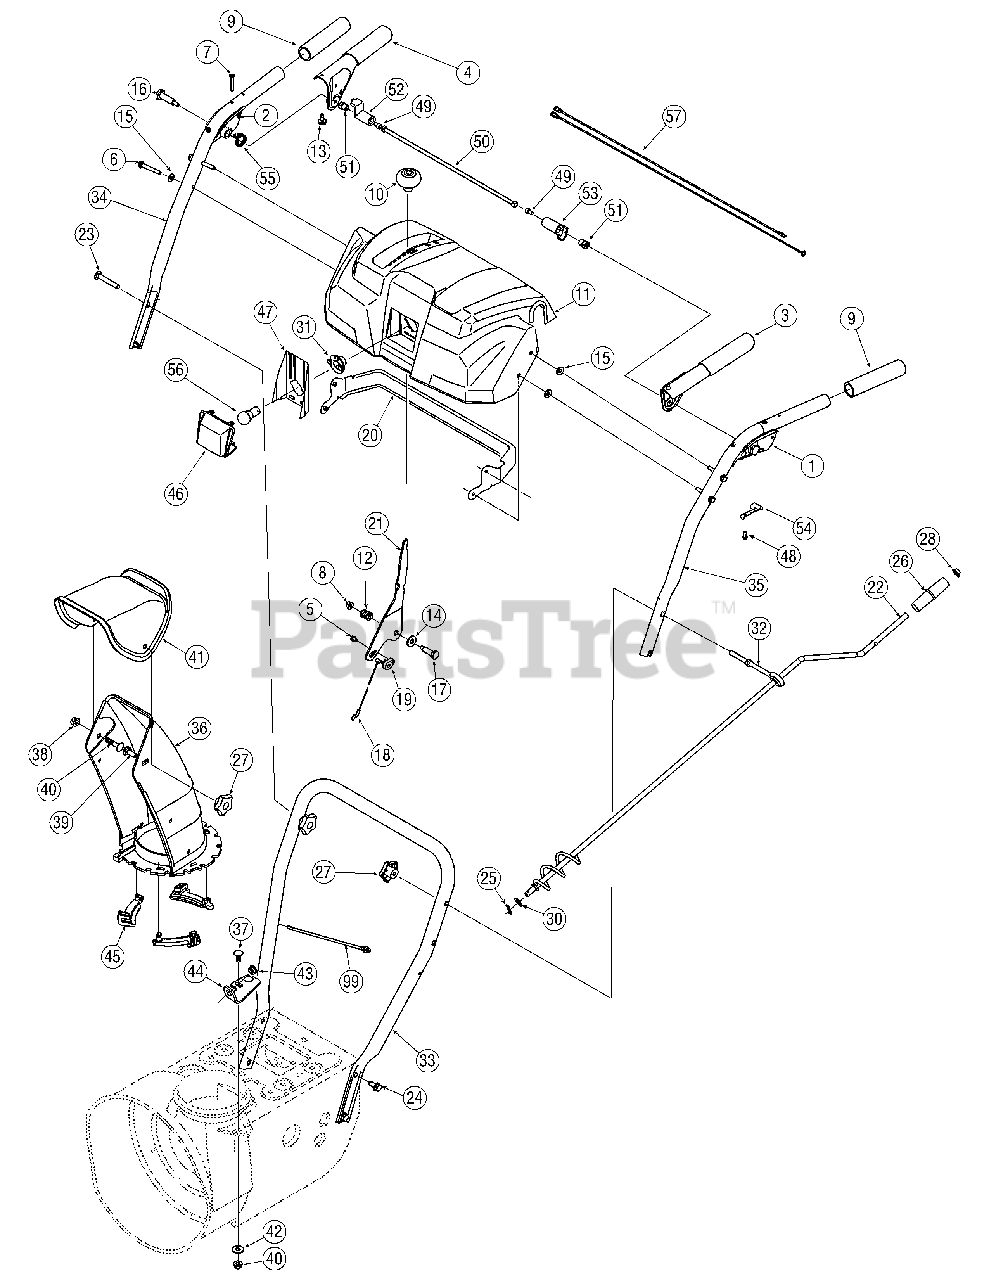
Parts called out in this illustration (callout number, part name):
1	Handle Assembly, Lock, LH
2	Handle Assembly, Lock, RH
3	Handle Ass’ y, Engagement LH
4	Handle Ass’y, Engagement, RH
5	Screw, #10-16, 0.500
6	Screw, 1/4-20, 1.750
7	Screw, Machine, #10-24, 1.375
8	Nut, Flange Lock, 1/4-20, Nylon
9	Grip, 1.0 ID x 5.0
10	Knob, Shift
11	Handle Panel, O-Style
12	Spring, .39 x .60 x .88
13	Bumper, Rubber, .62 OD x .22
14	Washer, Flat, .385 x .870 x .092
15	Washer, Flat, .25 x .630 x .0515
16	Screw, Shoulder, .43 x 1.34, 1/4-20
17	Screw, Shoulder, .374 Dia. x 1.05
18	Cable, Speed Selector
19	Barrel Holder, Cable, LH
23	Screw, Carriage, 5/16-18, 2.25
24	Screw, 5/16-18, 0.75, Gr5
25	Pin, Cotter, .072 x 1.13
26	Crank Knob, 1.0 Dia. x 3.2, Black
27	Knob Assembly, Wing Nut, 5/16-18
28	Cap, Push, 3/8 Rod
29	Grommet, .44 ID x .94 OD x .50
30	Washer, Flat, .375 x .738 x .063
31	Light Socket
32	Eye Bolt, Chute Crank
36	Chute, Lower, 5.0 Diameter
37	Bolt, Carriage, 5/16-18, 1.0
38	Nut, Flange Lock, 5/16-18, Nylon
39	Bolt, Carriage, 5/16-18, 1.0
40	Bolt, Carriage, 5/16-18, .750
41	Chute, Upper, w/ Label
42	Washer.349 ID x .879 OD x .063
43	Bushing, Plastic, .380
45	Flange Keeper, Chute
47	Reflector Label, Lens
48	Screw, #8-16 x 0.50
49	Screw, 1/4-20 x.375
50	Pivot Rod
51	Shoulder Nut, 1/4-20
52	Lock Plate
53	Clutch Lock Cam
54	Clutch Lock Spring
55	Torsion Spring
56	Lamp
57	Wire Harness
